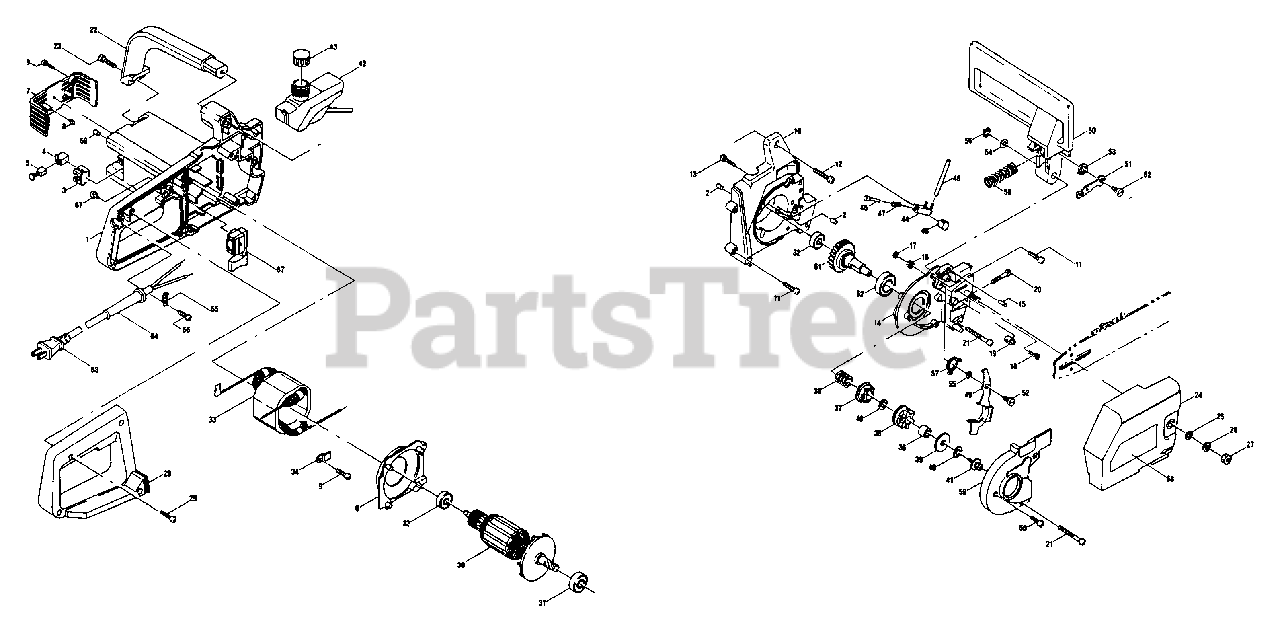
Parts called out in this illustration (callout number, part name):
1	CASE - LEFT
2	BUSHING
3	HOLDER, (A)
4	HOLDER, BRUSH
6	COVER
7	COVER
8	HOLDER, (B)
9	SCREW
10	CASE - RIGHT
11	SCREW - TAPPING
13	SCREW - TAPPING
14	GEAR CASE ASSY
15	PIN
17	WASHER - STAR
18	CONNECTOR
19	TENSIONER, CHAIN
20	SCREW
21	SCREW
22	HANDLE - FRONT
23	SCREW
24	BAR MOUNT ASSY
25	WASHER - 8
26	LOCKWASHER - 8
27	NUT - 8
28	HANDLE - RIGHT
29	SCREW - TAPPING
30	ARMATURE
31	BEARING, BALL - 6000
32	BEARING, BALL - 627ZZ
33	FIELD
35	SPROCKET
36	BUSHING
37	CLUTCH
39	PLATE, SIDE
40	WASHER
42	OIL TANK ASSY
43	CAP
44	OIL PUMP CASE ASSY
45	PISTON ASSY
46	TUBE
49	BRAKE LEVER ASSY
50	PROTECTOR ASSY
51	RATCHET
53	SPRING
54	WASHER
55	WASHER - 5
56	RING, RETAINING - 8
57	SPRING
58	SPRING
59	COVER, BRAKE
60	SCREW - 4X14
61	GEAR ASSY
62	BEARING, BALL - 6002
63	POWER CORD
64	CORD PROTECTOR
66	SCREW
67	SWITCH
68	NAME PLATE
69	BUSHING
